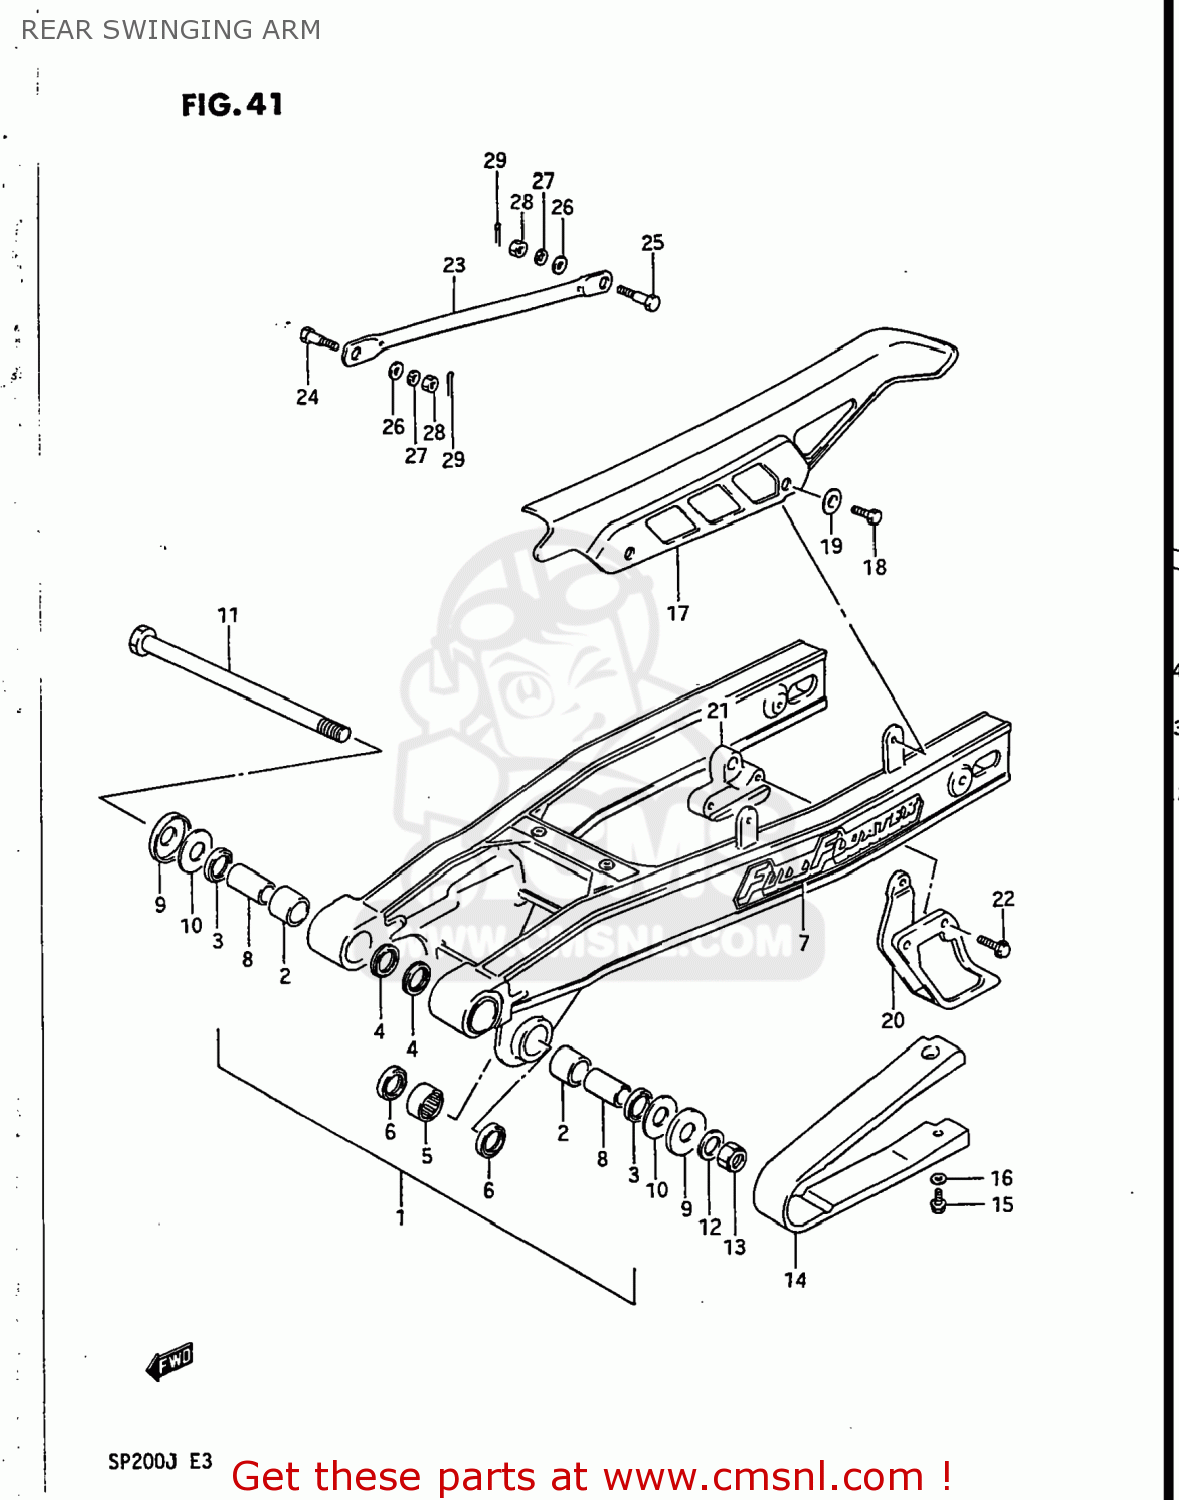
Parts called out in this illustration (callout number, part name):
1	SWING ARM ASSEMBLY,REAR
2	BUSHING,RR SWGARM PIVOT
3	OIL SEAL
4	SEAL,OIL(20X27X5)
5	BEARING
6	SEAL,CUSHION LEVER OUT DUST
7	EMBLEM
8	SPACER,RR SWGARM PVT
9	COVER,RR SWGARM DUST SEAL
10	WASHER
11	SHAFT,REAR SWING ARM
12	WASHER
13	NUT
14	BUFFER,CHAIN TOUCH DEFLECTOR
15	BOLT
16	WASHER
17	CASE,CHAIN
18	BOLT
19	WASHER
20	GUIDE,CHAIN
21	RUBBER,CHAIN GUIDE
22	BOLT
23	TORQUELINK,RR
24	BOLT,TORQUE LINK,FRONT
25	BOLT(8X26.5)
26	WASHER
27	LOCK WASHER
28	NUT
29	PIN 20X20
